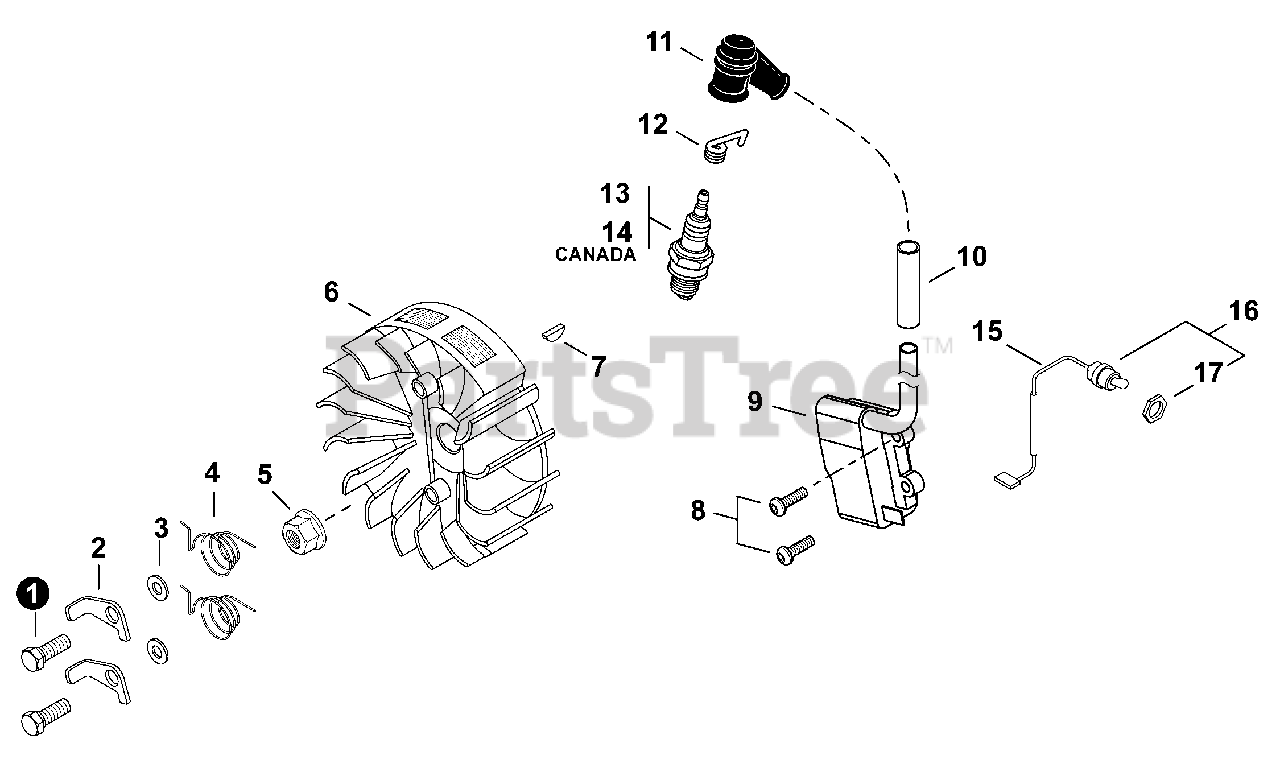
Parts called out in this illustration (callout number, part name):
3	WASHER 6
4	SPRING, TORSION
5	NUT M8×1.0
6	FLYWHEEL
7	KEY, WOODRUFF 3×10
8	BOLT, ADHESIVE M4×20
9	COIL ASSY, IGNITION
10	TUBE, INSULATOR
11	CAP, SPARK PLUG
12	TERMINAL, SPARK PLUG
13	SPARK PLUG - BPM8Y
14	SPARK PLUG - BPMR8Y
15	LEAD - IGNITION
16	SWITCH ASSY, ON-OFF
